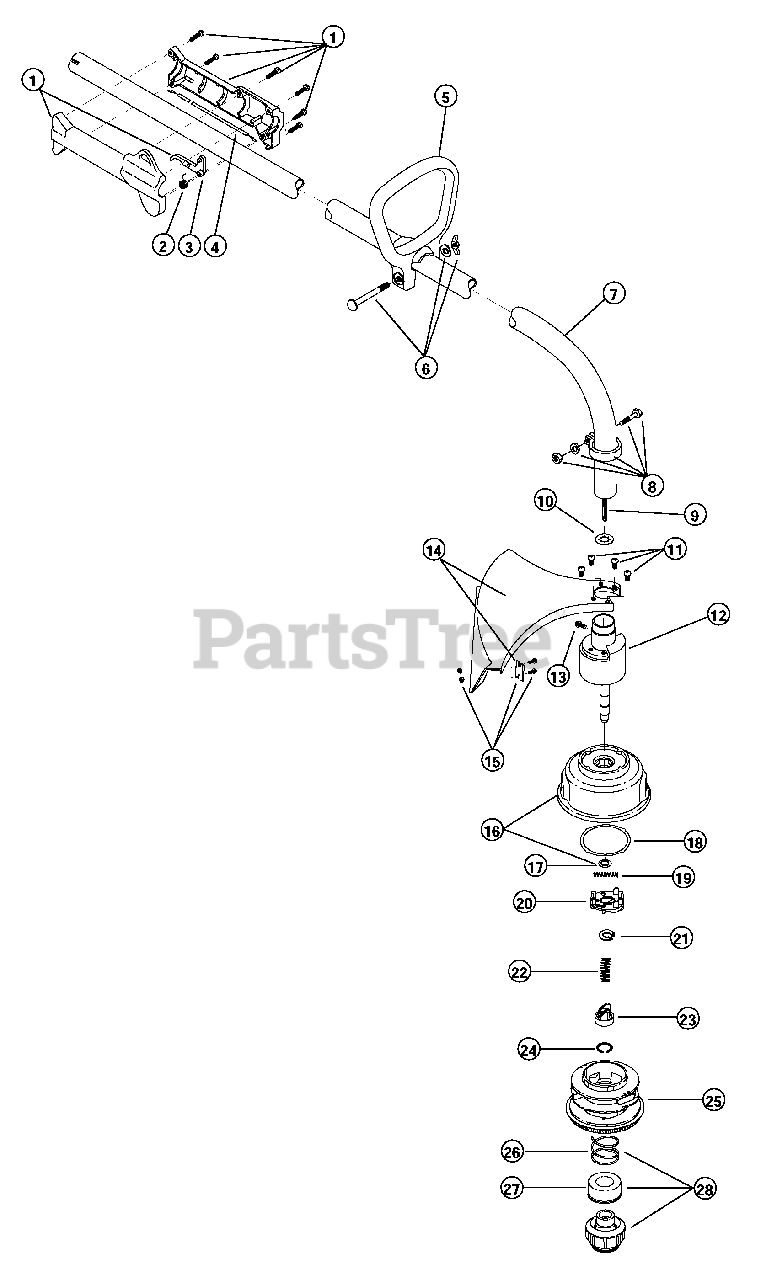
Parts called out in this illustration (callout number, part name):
1	Throttle Housing Assembly
2	Throttle Trigger Spring
3	Throttle Trigger
4	Throttle Cable Assembly
5	D-Handle Assembly
6	D-Handle Hardware
7	Drive Shaft Housing Assembly
8	Lower Clamp Assembly
9	Flexible Drive Shaft
10	Palnut
11	Shield Mounting Screw
12	Bushing Housing Assembly
13	Anti-Rotation Screw
14	Shield and Blade Assembly
15	Blade Assembly
16	Outer Spool Assembly
17	Retainer
18	Thrust Washer
19	Small Spring
20	Slider
23	Plunger
25	Inner Reel
26	Large Spring
27	Foam Seal
28	Bump Head Knob Assembly
